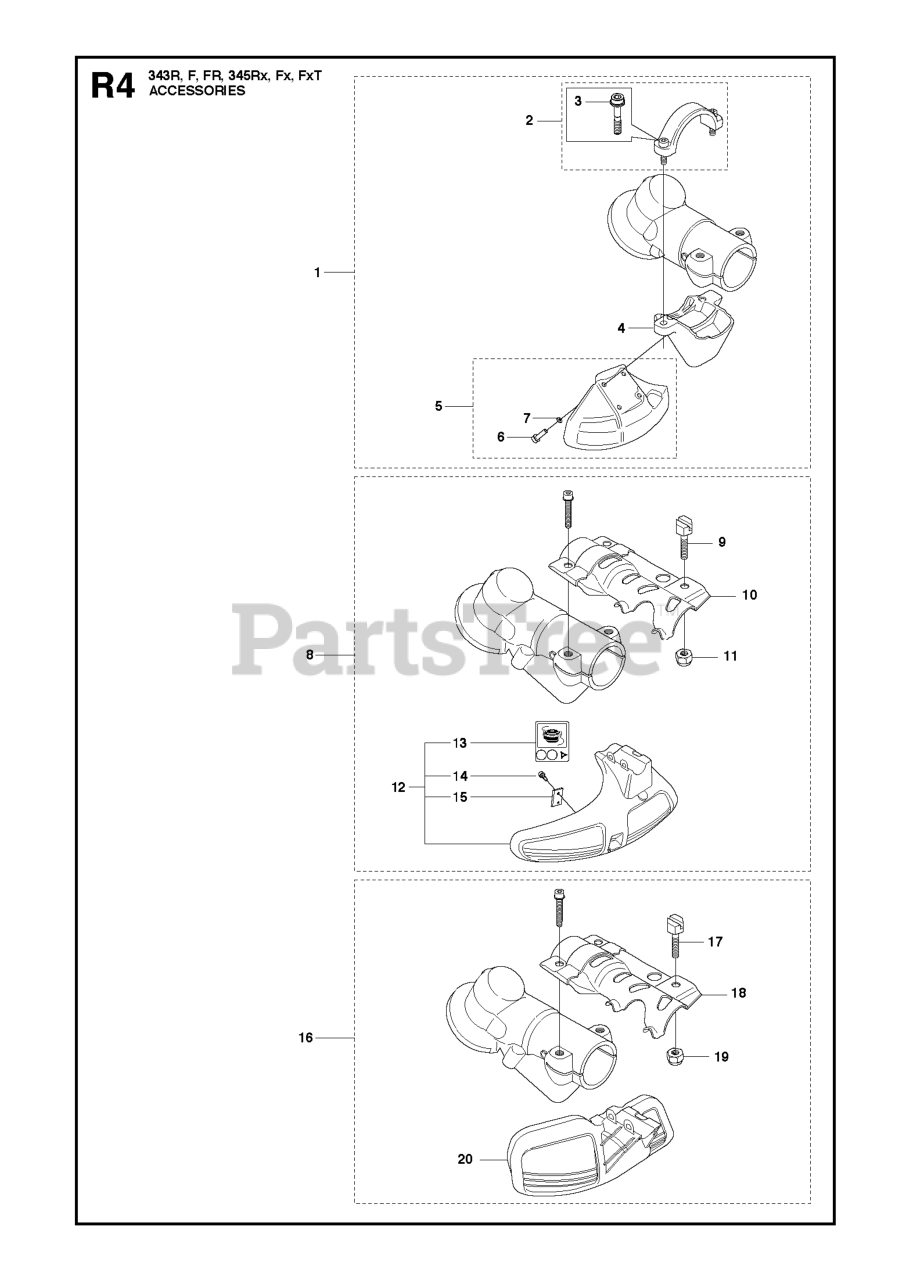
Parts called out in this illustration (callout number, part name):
1	TRIMMER GUARD ASSY
2	CLAMP
3	SCREW IHSCFMO
5	RP BLADE GUARD
7	LOCKING NUT
8	TRIMMER GUARD ASSY
11	LOCKNUT M6
16	TRIMMER GUARD COMPL
19	LOCKNUT M6
20	BLADE GUARD
